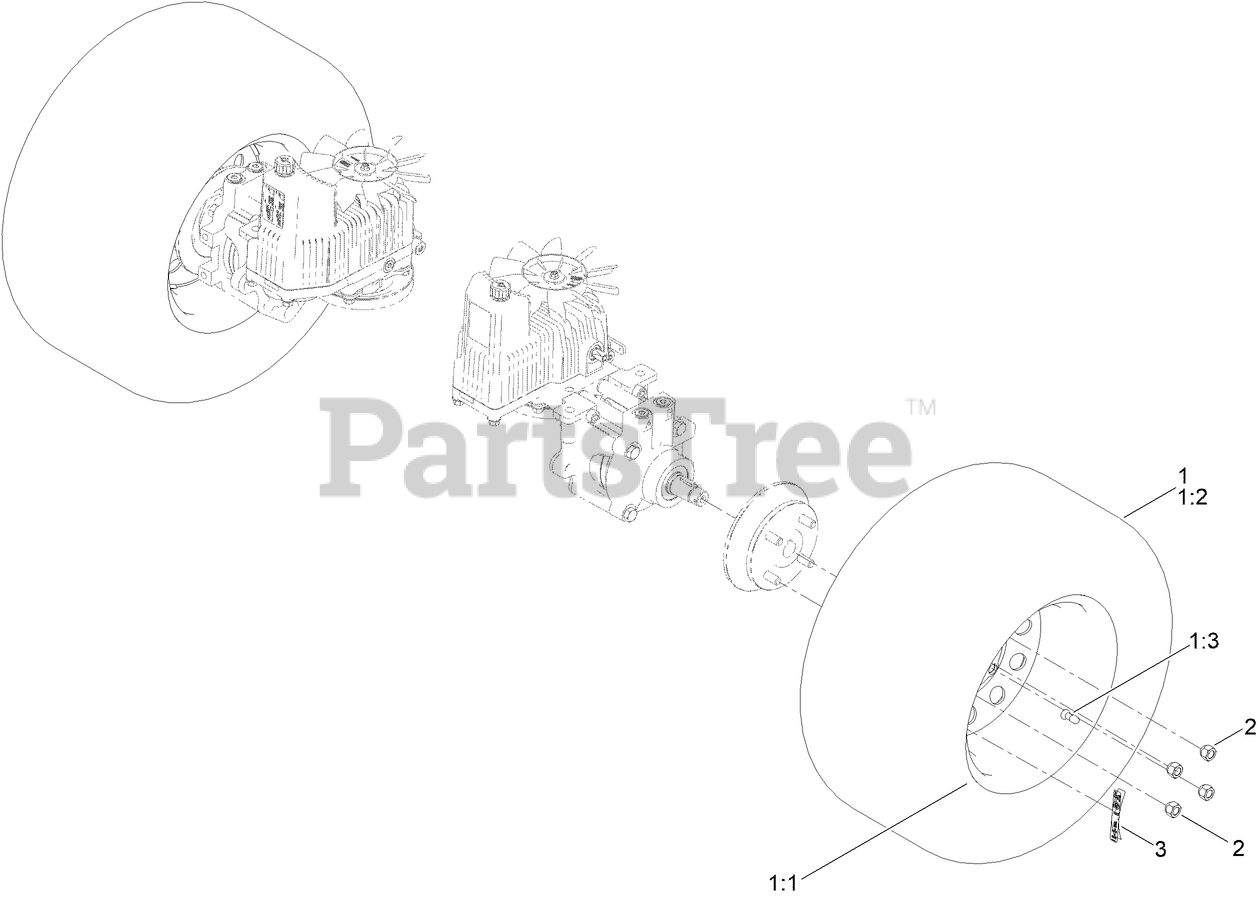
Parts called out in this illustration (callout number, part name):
1	WHEEL AND TIRE ASM
1:2	TIRE-24X12-12
2	NUT-LUG
3	DECAL-TORQUE, WHEEL HUB LUG
